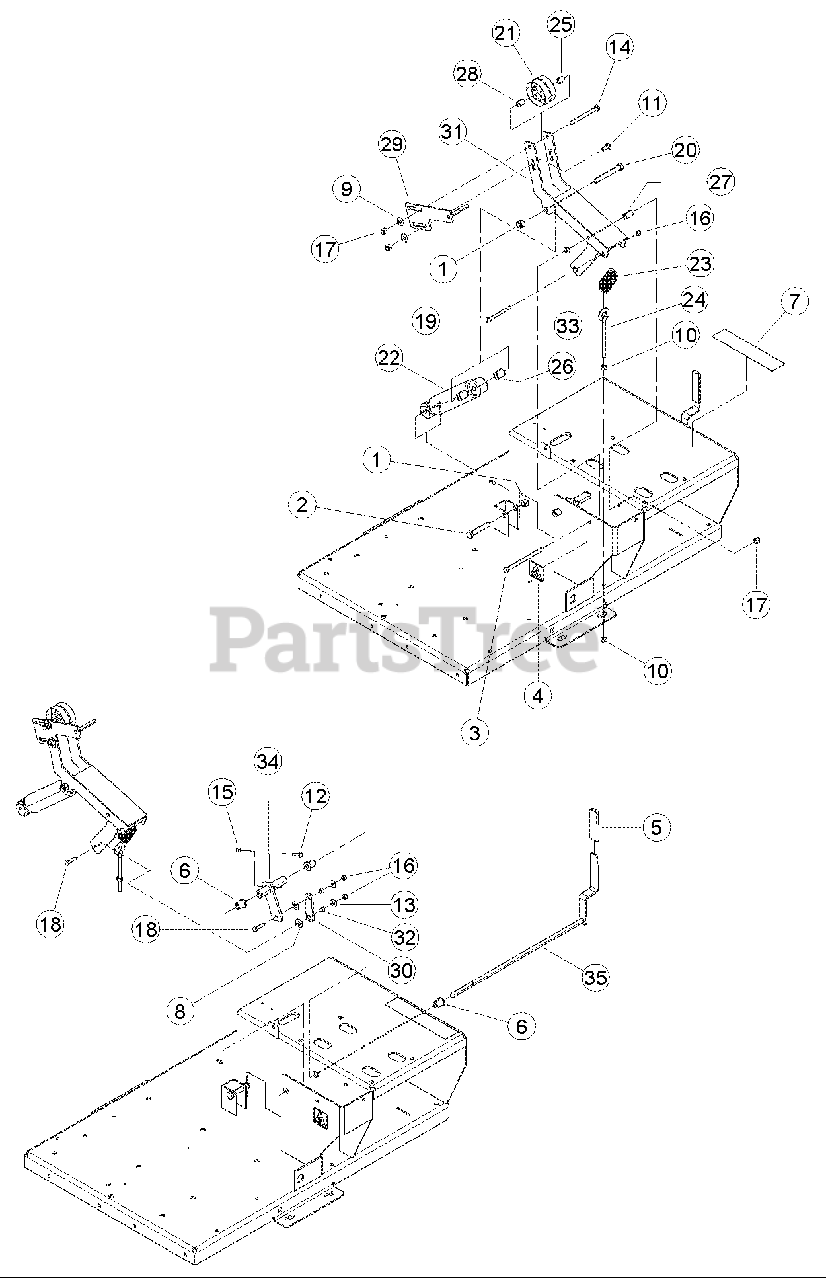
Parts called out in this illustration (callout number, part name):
1	NUT, 1/2-13 UNC NYLOCK
2	BOLT, 1/2 X 2-3/4 HEX GR5 ZP
3	BOLT, 3/8 X 5-1/2 HEX GR5 ZP
4	DECAL, SHIELD DANGER ISO
5	GRIP, CLUTCH HANDLE
6	BUSHING, 1/2 X 1 FLANGE LUBE
7	DECAL, CHIPPER ENGAGEMENT
8	NYLON WASHER, 1/2 INCH
9	WASHER, 3/8 FLAT ZP
10	NUT, 3/8 HEX NC ZP
11	BOLT, 3/8 X 1 CRG GR5 NC ZP
12	BOLT, 1/4 X 1-1/4 HEX HD GR5 ZP
13	WASHER, 5/16 FLAT ZP
14	BOLT, 3/8 X 4 HEX HD GR5 NC ZP
15	NUT, 1/4 NE NYLOCK ZP
16	NUT, 5/16 NE NYLOCK ZP
17	NUT, 3/8 NE NYLOCK ZP
18	BOLT, 5/16 X 1-1/4 HEX HD GR5 NC ZP
19	BOLT, 5/16 X 3-1/2 CRG GR5 ZP
20	BOLT, 1/2 X 3-3/4 HEX HD GR5 NC ZP
21	PULLEY, 3-1/4 FLAT IDLER
22	ABSORBER, IDLER SHOCK
23	SPRING, 1.25 OD X 3.50 LG X .148 WD
24	EYEBOLT, 3/8 X 5 LG 4-1/4 THD ZP
25	SPACER, .63 X .63 PULLEY
26	SPACER, .75 X .59
27	SPACER, .63 X 1.035
28	SPACER, 5/8 OD X 11 GA X .760
29	WELDMENT, PIVOT ROD
30	PLATE, CONNECTING ARM
31	WELDMENT, IDLE ARM
32	SPACER, 1/2" OD X 14 GA WA X 0.26"
33	SPACER, 5/8" OD X 3/8" ID X 0.28"
34	WELDMENT, PIVOT ARM
35	WELDMENT, HANDLE
